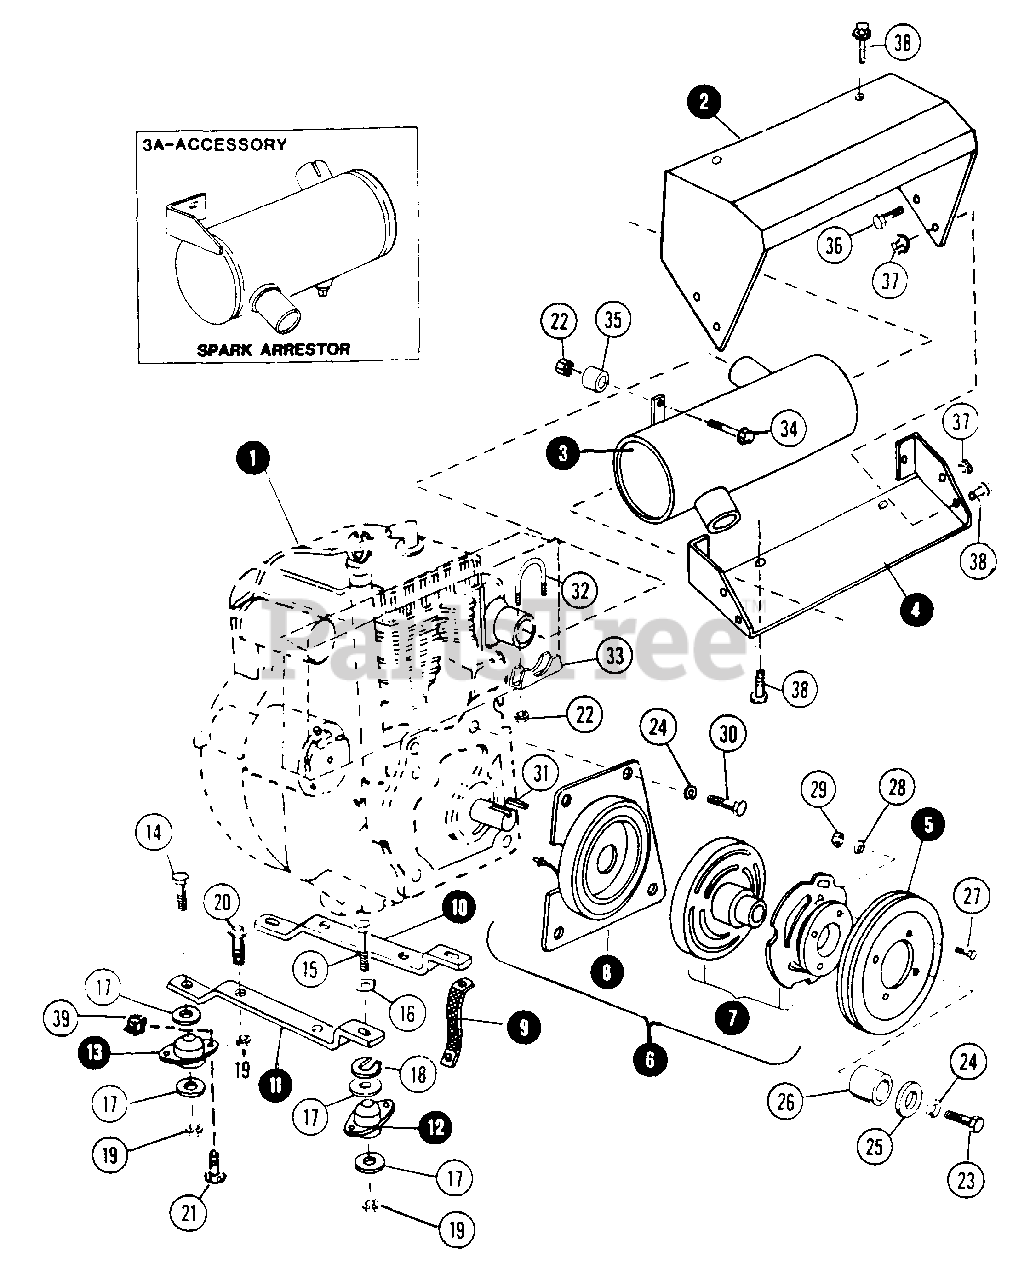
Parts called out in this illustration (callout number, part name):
2	SHIELD UPPER-MUFFLER HEAT
3	MUFFLER (STANDARD)
3A	MUFFLER, SPARK ARRESTOR
4	SHIELD, LOWER - MUFFLER HEAT
5	PULLEY, DRIVE
6	CLUTCH ASSEMBLY
7	ROTOR ASSEMBLY
8	FIELD ASSEMBLY
9	STRAP, ENGINE GROUND
10	RAIL, LEFT ENGINE MOUNTING
11	RAIL, RIGHT ENGINE MOUNTING
12	DAMPER, ENGINE FRONT
13	DAMPER, ENGINE REAR
14	BOLT, 3/8C x 2 HEX HEAD
15	BOLT, 3/8C x 3 HEX HEAD
16	WASHER, 3/8 SAE FLAT
17	WASHER, DAMPER SNUBBING
18	C-WASHER
19	NUT, 3/8C HEX FLANGE LOCK
20	BOLT, 3/8C x 1-1/4 HEX FLANGE LOCK
21	BOLT, #10-24 x 3/4 FLANGE LOCK
22	NUT, 5/16C HEX LOCK
23	BOLT, 7/16F x 1-1/4 FLAT
24	WASHER, 7/16 LOCK
25	WASHER, SPECIAL FLAT
26	SPACER, 1-1/8 x 1-3/8 x 1-1/4
27	BOLT 1/4C x 3/4 HEX HEAD
28	WASHER, 1/4 LOCK
29	NUT, 1/4C HEX
30	BOLT, 7/16C x 7/8 HEX HEAD
31	KEY, 1/4 SQUARE x 5/8"
34	BOLT, 5/16C x 2 HEX FLANGE LOCK
35	SPACER, STEEL
36	BOLT, 1/4C x 3/4 DRILLED HEAD
37	NUT, 1/4C HEX FLANGE LOCK
38	BOLT, 1/4C x 1/2 HEX FLANGE LOCK
39	NUT, #10-24 FLANGE LOCK
